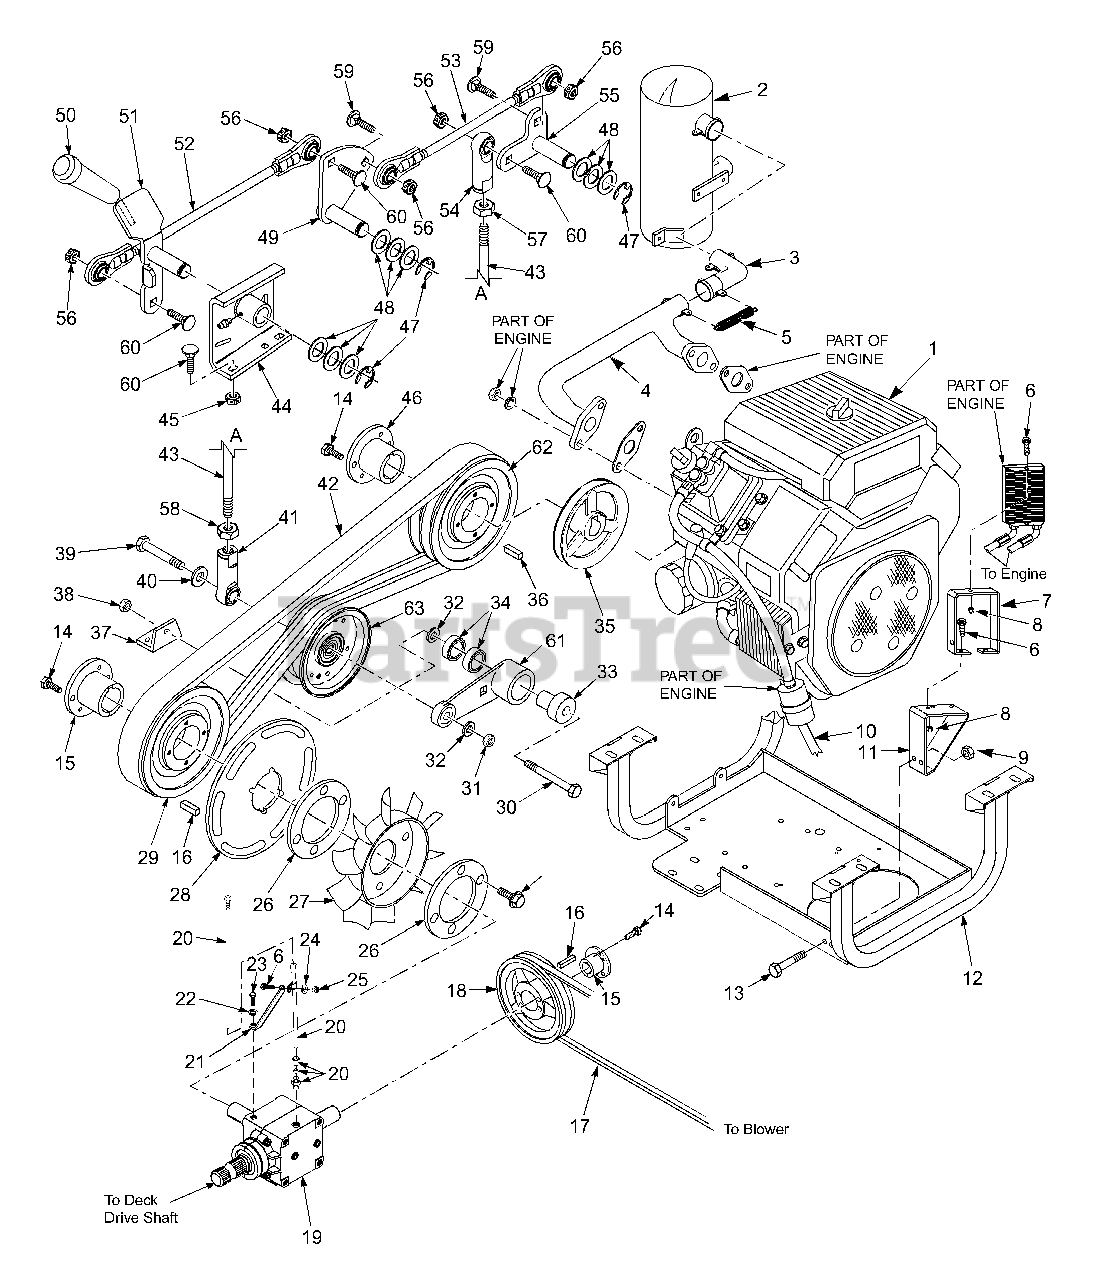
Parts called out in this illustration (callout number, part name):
1	Engine, 25 HP Kohler (Spec. PS-68650)
2	Muffler
3	Pipe, Exhaust
4	Manifold, Exhaust, Kohler
5	Spring, Exhaust
6	Bolt, Hex Head 1/4-20 x .75"
7	Guard, Oil Cooler, Kohler Only
8	Nut, Serrated Flange 1/4-20
9	Nut, Elastic Stop 3/8-16
10	Hose, Fuel 1/4" ID (order by the inch)
11	Bracket, Oil Cooler, Kohler Only
12	Weldment, Engine Deck
13	Bolt, Hex Head 3/8-16 x 1.5"
14	Capscrew, Hex Head 1/4-20 x 1"
15	Hub, Tapered 1" Bore
16	Key, 1/4 x 1/4 x 1.25"
17	Belt, Blower
18	Pulley, 5.35" OD
19	Gearbox, T-Drive
20	Dipstick Assembly
21	Bracket, Dipstick Tube
22	Lock Washer, 5/16"
23	Bolt, Hex Head 5/16-18 x 3/4"
24	Flatwasher, 1/4-.312 x .750 x .065
25	Nut, Elastic Stop 1/4-20
26	Spacer, Fan
27	Fan, Cooling
28	Disk, Fan Support
29	Pulley, 4.95" OD Tapered Bore
30	Bolt, Hex Head 3/8-16 x 2.5"
31	Nut, Elastic Stop 3/8-16
32	Lock Washer, 3/8"
33	Pivot, Idler
34	Bearing, Idler Arm
35	Pulley, 5.45" OD - 1.125 Bore
36	Key, 1/4 x1/4 x 1"
37	Mounting Bracket, Idler
38	Nut, Elastic Stop 3/8"
39	Bolt, Hex Head 3/8-16 x 4"
40	Lock Washer, 3/8"
41	Rod End, 3/8-24 LH Female
43	Link, PTO
44	Bracket, PTO
45	Nut, Elastic Stop 3/8-16
46	Hub, Tapered 1.125" Bore
47	External E-Ring
48	Flatwasher, 3/4-.766 x 1.25 x .105
49	Bellcrank Weldment, Front
50	Grip, PTO Lever
51	Lever Weldment, PTO Engagement
52	Linkage Assembly, PTO Upper
53	Linkage Assembly, PTO Center
54	Rod End, 3/8-24 RH Female
55	Bellcrank Weldment, Rear
56	Nut, Center Lock 3/8-16
57	Nut, 3/8-24 LH Thread
58	Nut, 3/8-24 RH Thread
59	Bolt, Carraige 3/8-16 x 1-1/2"
60	Bolt, Carraige 3/8-16 x 1"
61	Idler Arm
62	Pulley, 4.95" OD Tapered Bore
63	Pulley, Idler 4" Dia.
